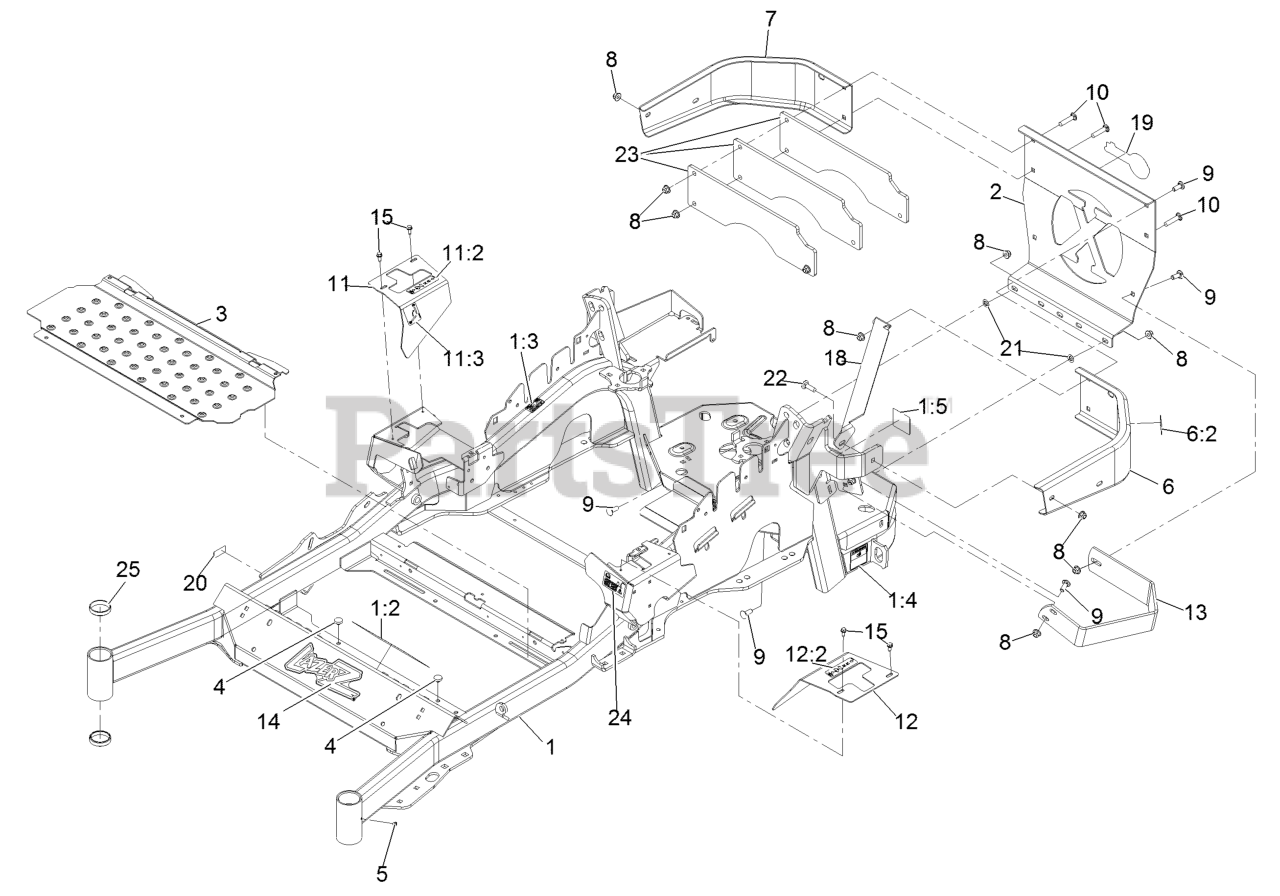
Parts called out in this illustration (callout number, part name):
1	MAINFRAME ASM
1:2	DECAL-WARNING
1:3	DECAL-WARNING, SLOPE
1:4	DECAL-HAZARD, PINCHED FINGER
1:5	DECAL-SPARK ARRESTER
2	PLATE,REAR GUARD
6	LH BUMPER ASM
6:2	DECAL-WARNING
7	BUMPER-RH
8	NUT-HF, NI
9	SCREW-CARR
10	SCREW-CARR
11	RH MOTION CONTROL COVER ASM
11:2	DECAL-CONTROL, MOTION
11:3	DECAL-PARK BRAKE, CE
12	LH MOTION CONTROL COVER ASM
12:2	DECAL-CONTROL, MOTION
13	GUARD-MUFFLER
14	DECAL,LAZER MODEL
15	SCREW-HWH
20	Decal-Patent Ttco.Com
21	NUT-PUSH
22	BOLT-CARR
23	PLATE-WEIGHT, 6 LB
24	DECAL-FUEL FILL, CE
25	CUP-BEARING
